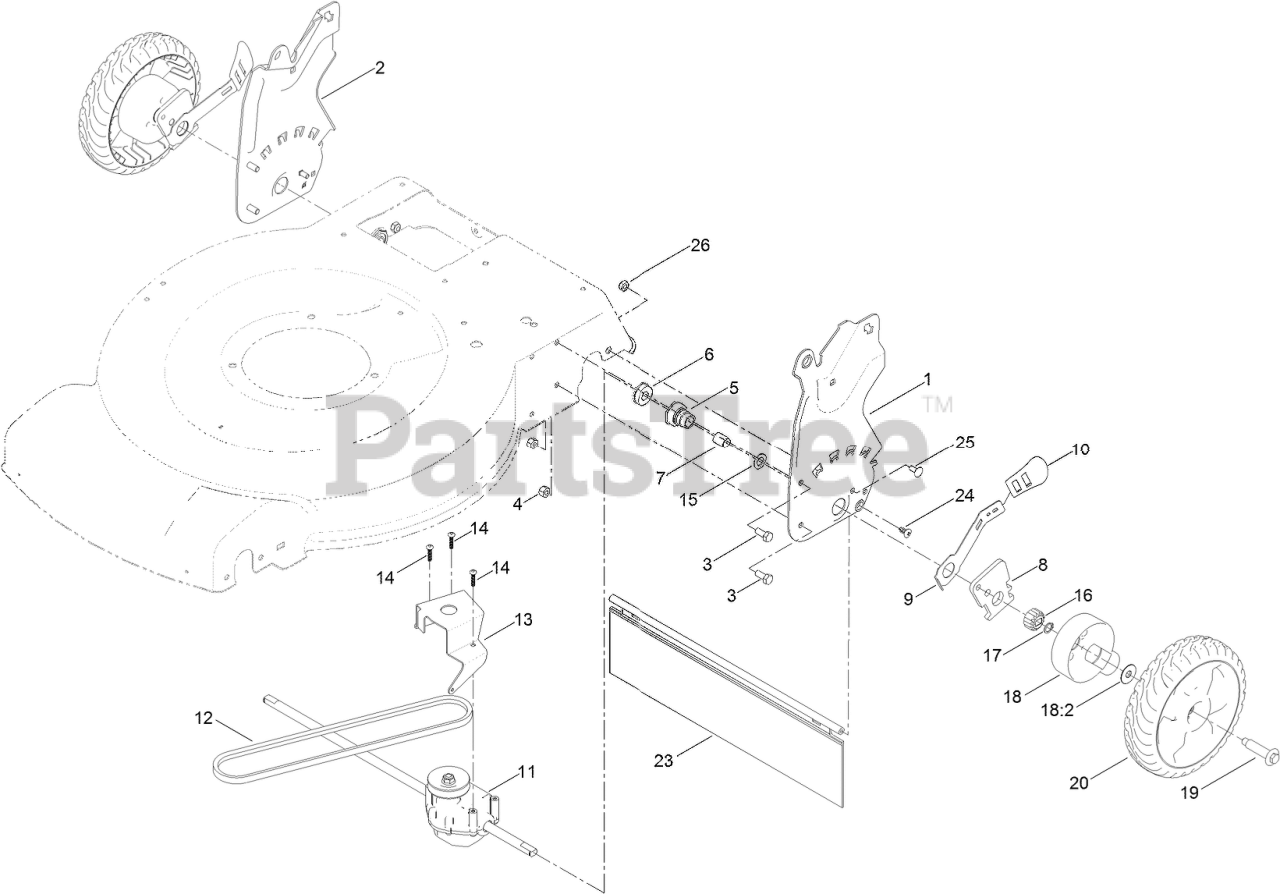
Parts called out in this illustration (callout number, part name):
1	PLATE-HOC, LH
2	PLATE-HOC, RH
3	SCREW-HH
4	NUT-LOCK, NI
5	RETAINER-BUSHING, HOC
6	BEARING-BALL
7	BUSHING-SLEEVE
8	ARM-PIVOT, REAR
9	ARM-SPRING
10	KNOB-HOC
11	TRANSMISSION ASM
12	BELT-V
13	BRACKET-TRANSMISSION
14	SCREW-PLASTITE
15	WASHER-THRUST
16	GEAR-PINION, 15T
17	RING-RETAINING
18	GEAR COVER ASM
18:2	WASHER-STEPPED
19	BOLT-SHOULDER
20	8 INCH WHEEL GEAR ASM
23	SHIELD-TRAILING
24	SCREW-PTH
25	SCREW-CARR
26	NUT-LOCK, NI
